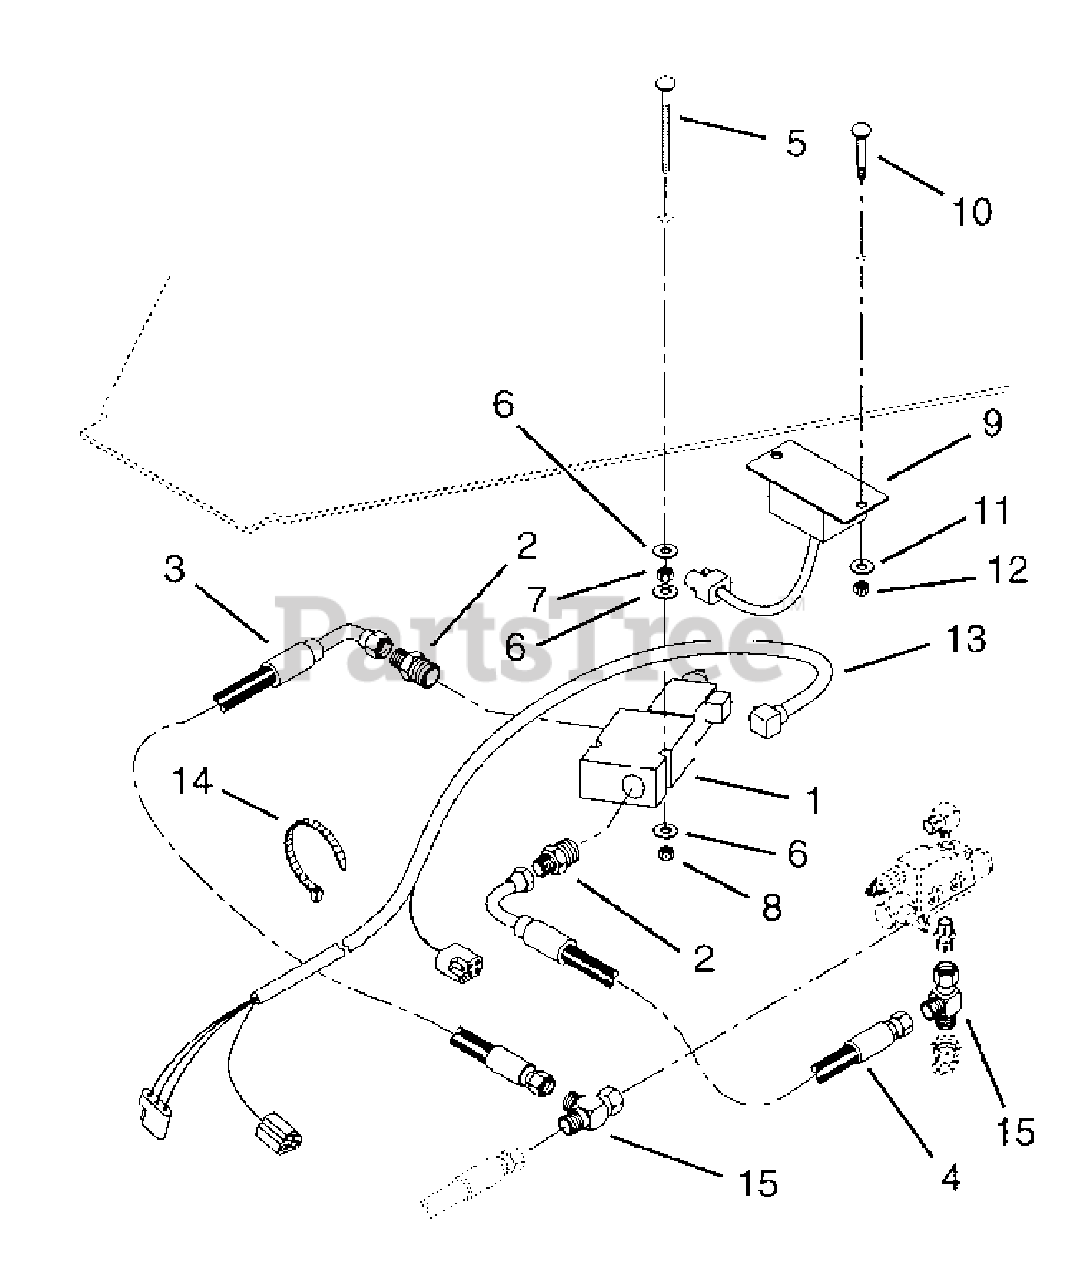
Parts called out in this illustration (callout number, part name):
1	Valve - Autofeed
2	Adapter-Hydraulic st 1-1/16
3	Hose-Hydraulic 30" with elbow
4	Hose-Hydraulic 26.5" with elbow
5	Bolt-round head square neck .25-20x2.75
6	Washer-flat-steel .38x.875x.083
7	Nut .31-18
8	Nut-Locking-Center .31-18
9	Module-Autofeed
10	Bolt-round head square neck .25-20x1.00
11	Washer-flat-steel .312x.734x.065
12	Nut-Locking-Center .25-20
13	Harness-Wiring Autofeed
14	Tie Wrap
15	Swivel-Tee
